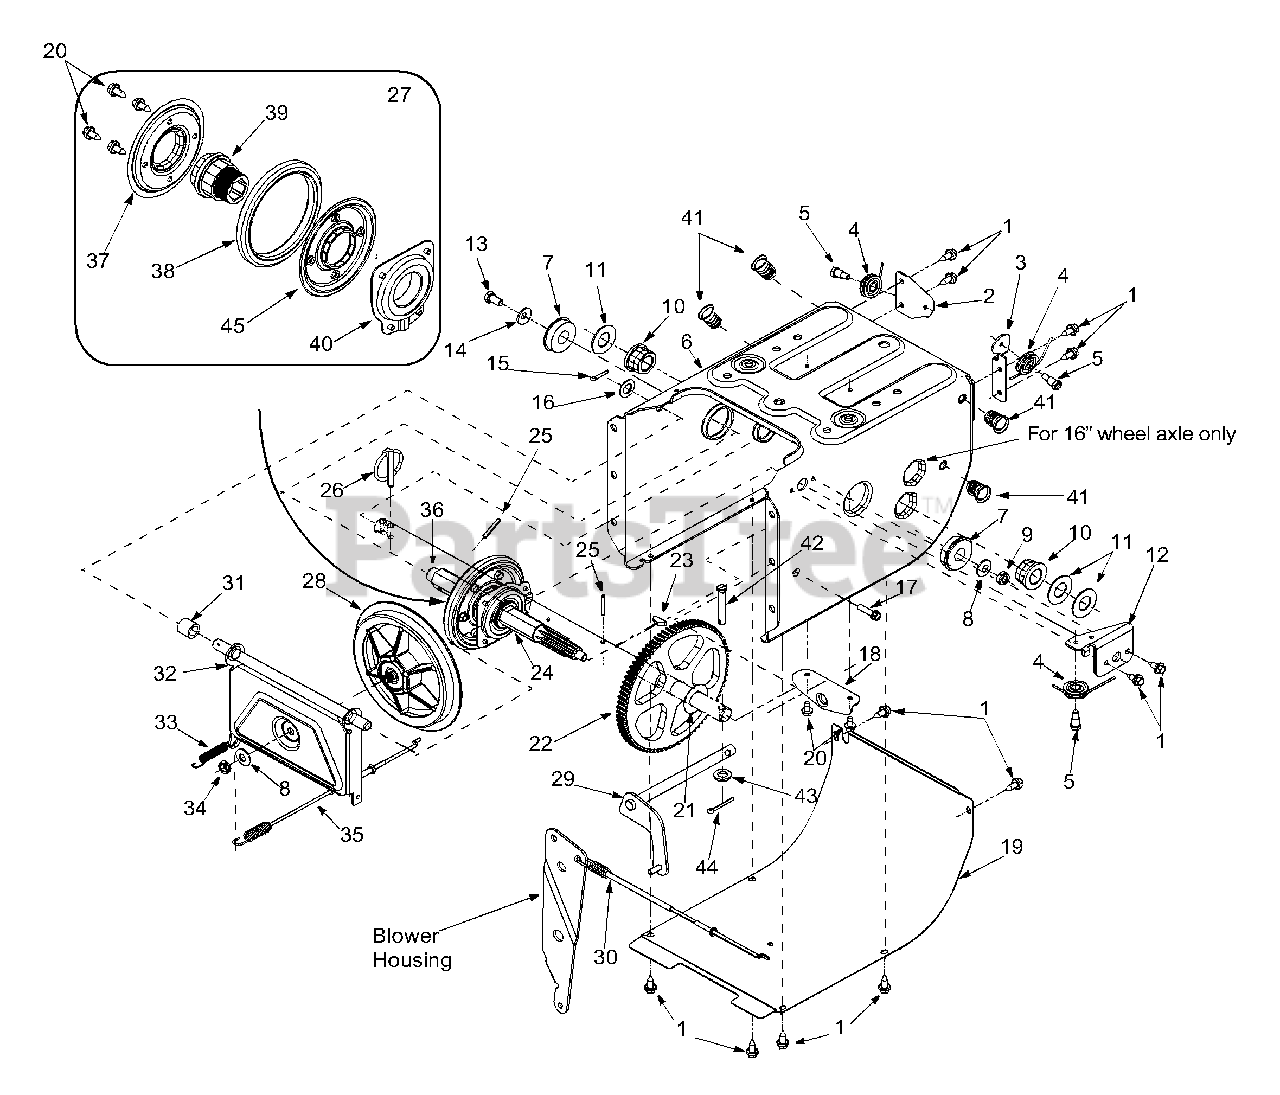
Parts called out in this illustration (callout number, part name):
1	Self-Tapp. Screw 1/4-20 x 0.5"
5	Hex Screw 1/4-28
8	Bell Washer
9	Lock Jam Nut
10	Hex Flange Bearing
11	Flat Washer
14	Bell Washer .340 ID x .872 OD
15	Cotter Pin
16	Flat Washer .536 ID x .930 OD
17	Hex Washer Screw 1/4-20 x .625"
21	Flat Washer .760 ID x .50 OD
24	7-Tooth Shaft
25	Roll Pin
26	Klik Pin
27	Friction Wheel Assembly
28	Friction Disc Wheel
29	Wheel Shift Rod Assembly
30	Drive Cable, Auger
31	Spacer
34	Jam Nut 3/8-24
35	Drive Cable, Clutch
36	22 .2" Axle (Used w/ 13 x 4 tire)
36	21.4" Axle (Used w/ 13 x 5 tire)
37	Friction Plate
38	Friction Wheel Rubber
39	Friction Wheel Hub
40	Friction Wheel Bearing
41	Nut Insert
42	Clevis Pin
43	Flat Washer .281 ID x .50 OD
44	Cotter Pin
